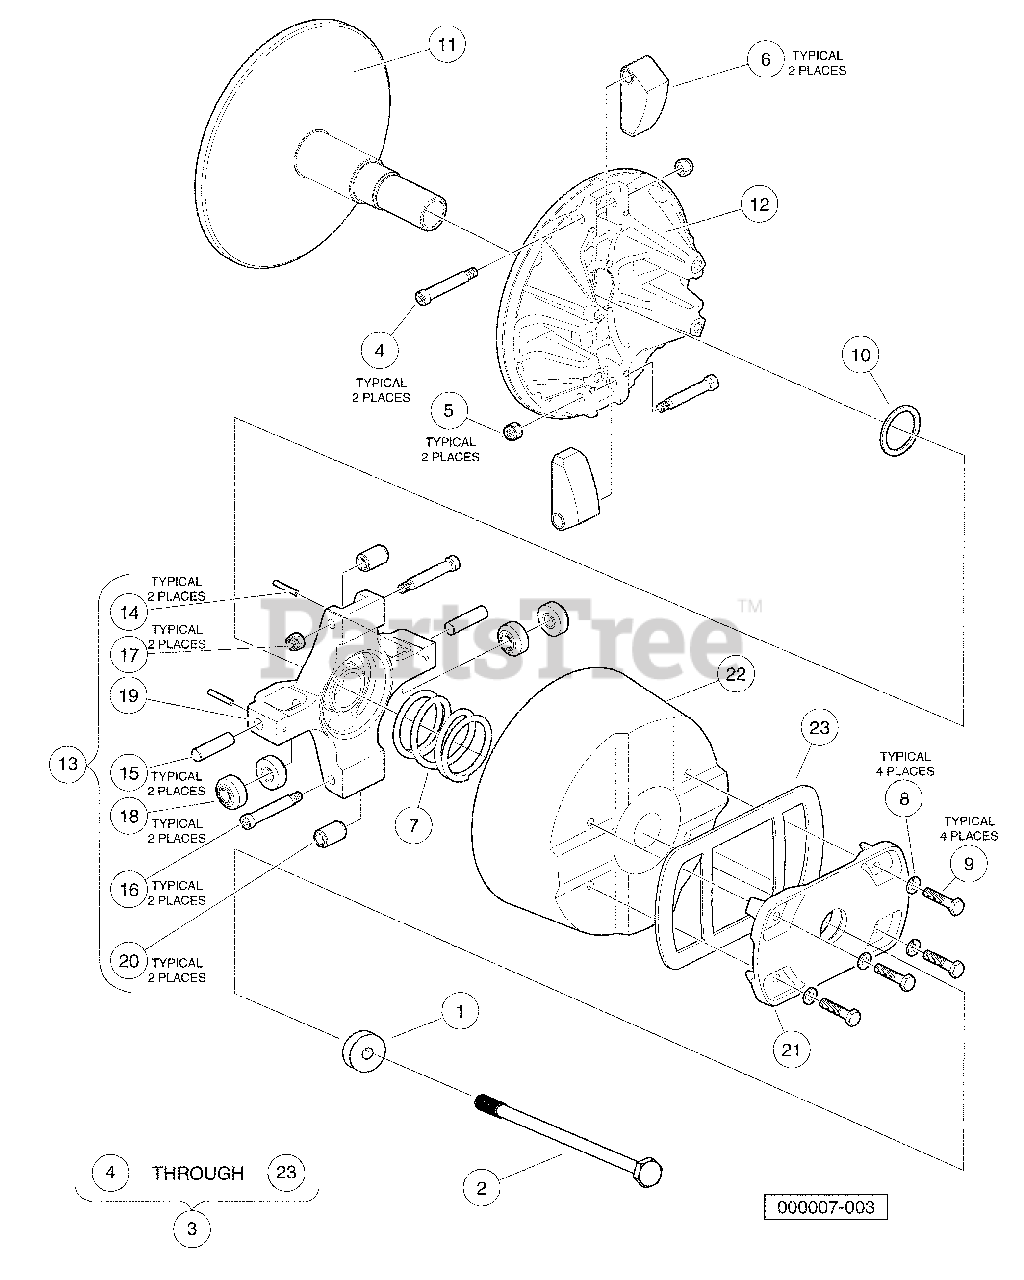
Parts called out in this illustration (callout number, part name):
1	Washer, Stepped
2	Bolt, M10x1.25x200 Loctite
3	Clutch, 4x4, Gas, W/cover
4	Screw, Shlder Hex, .312 X 1.75
5	Nut, Lock Hex, 1/14-20, Flexlc
6	Sub Assy, Wt Clutch, Gas
7	Spring, Compression, Primary
8	Washer, Lock, H-Spring, 1/4
9	Screw, Cap, Hex Hd, 1/4 X 1.25
10	Shim, 1.63 X 1.33
11	Subassembly, Drive Clutch
12	Subassembly, Moveable, Drive Clutch
13	Spider Subassembly (Gasoline)
14	Pin, Spring Slotted,1.25 X 1.0
15	Pin, Dowel, .375 X 1.50
16	Screw, Shlder Hex, .312 X 1.75
17	Nut, Lock Hex, 1/14-20, Flexlc
18	Roller, Torque, Gas
19	Spider, Drive Clutch
20	Sub Assy, Roller Weight
21	Cover, Drive Clutch
22	Cover, Clutch, 4x4
23	Gasket, Cover, Clutch, 4x4
